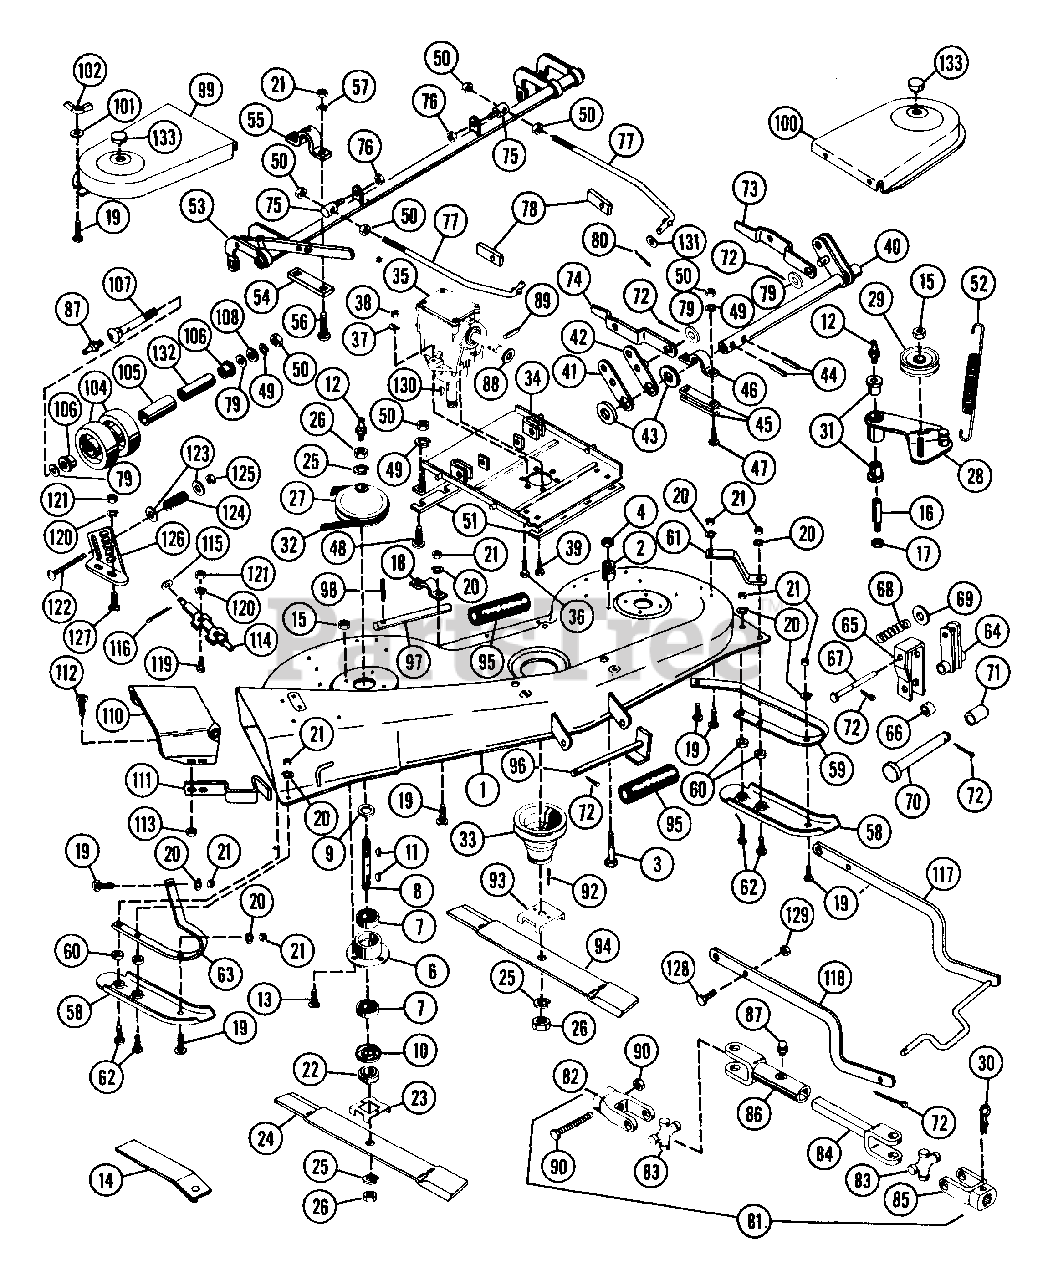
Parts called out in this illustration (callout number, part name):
1	60 INCH MOWER PAN W/ DECALS
2	SPRING ANCHOR
3	BLT-HEX .38-16X1.50 PL GR2
4	NUT-LK-CTR .375-16 GR A PL
6	HOUSING, SPINDLE
7	BRG-BALL .750X1.781X.61
8	SPINDLE SHAFT
9	WSHR-FL-STL .754X1.000X.032
10	BEARING SLINGER
11	KEY-WDRF .188X.625X.25 SAE 61
12	SPIN DRIVE ZERK FITTING
13	BLT-RDHDSQNK .38-16X.62 GR5 PL
15	NUT-LK-JAM-CTR .375-16 PL
16	IDLER STUD
17	NUT-LK-CTR .50-13
18	ROLLER CLAMP
19	BLT-RDHDSQNK .31-18X.75 GR5 PL
20	WSHR-LK .312X.097 PL HVY
21	NUT-HEX .312-18
22	RETAINER HUB
23	BLADE TRAY
24	MOWER BLADE 22 1/2
25	WSHR-LK .750X.188 MED PL
26	NUT-JAM .75-10 PL
27	SPINDLE SHEAVE
28	IDLER ARM
29	IDLER-FLAT 2.75 X .38 DAYCO
30	PIN-HAIR INT .18X1.18X3.25 PL
31	BSHG-FLG .625X.750X.500X.875BR
32	V-BELT, HA-WRAPPED
34	MOUNTING PLATE
35	MOWER GEAR CASE 48 IN
36	BLT-HEX .31-18X1.25 PL GR5
38	NUT-LK-TOP .312-18 GR C PL
39	SCR-TAP .312-18X1.0 THH PL TR
40	FRONT HANGER
41	OUTSIDE LINK
42	INSIDE LINK
43	WSHR-FL-STL .781X1.250X.059 PL
44	PIN-ROLL .250X1.25
47	BLT-RDHDSQNK .50-13X1.50 PL
48	BLT-RDHDSQNK .50-13X1.25GR5PL
49	WSHR-LK .500X.151 HVY PL
50	NUT .50-13 PL
52	SG-TENS .121X1.00X6.5 WLD 12
53	ROLLER FRAME
54	PAD
55	CLAMP
56	BLT-RDHDSQNK .31-18X1.00 PL
57	WSHR-LK .313X.093 MED HICLR
58	SKID
59	SKID BAR L.H.
60	SPACER .344X1.000X.375
61	BRACE
62	BLT-RDHDSQNK .31-18X1.50 GR5PL
63	SKID BAR R.H.
65	SUPPORT CHANNEL
66	SPACER .516X.749X.938
67	PIN-CLEV .498X4.31 YWZC
68	SG-COMP .62X.68X1.75
69	WSHR-FL-STL .531X1.062X.095 PL
70	PIN-CLEV .498X4.50 YWZC
71	SPACER .390X1.000X.562
72	PIN-COTR .12X1.0 PL
73	LEVELING LEVER L.H.
74	LEVELING LEVER R.H.
76	NUT-LK-CTR .50-13
77	ADJUSTMENT ROD
78	WEAR PLATE
79	WSHR-FL-STL .511X1.441X.125 PL
80	PIN-COTR .12X.75 PL
81	PTO ASSEMBLY
83	JOURNAL CROSS & BEARING ASSEMB
84	YOKE AND SHAFT
86	SLIP YOKE
87	SPIN DRIVE ZERK FITTING
88	WSHR-FL-STL .754X1.000X.032
89	PIN-ROLL .125X1.00
90	SHEARBOLT & NUT ASSEMBLY
92	PIN-GRV .188X.75 TP A
93	BLADE TRAY
94	BLADE
96	PIN WELDMENT
98	PIN-ROLL .250X1.00
99	BELT COVER R.H.
100	BELT COVER L.H.
101	WSHR-FL-STL .38X.875X.083 PL
102	NUT-WING W/INSERT .312 - 18
104	WHL 5 IN O.D.
105	WHEEL HUB
106	BRG-BALL .500X1.125X.500
107	WHEEL BOLT
108	WSHR-FL-STL .505X.880X.072 PL
110	CHUTE EXTENSION
111	SPRING, FLAT
112	BLT-RDHDSQNK .25-20X.50 SHT PL
113	NUT-LK-CTR .250-20 PL
114	HINGE PIN
115	WSHR-FL-STL.406X.812X.065PL
116	PIN-COTR .09X.75 PL
117	MOWER HANGER
118	HANGER ARM
119	BLT-SERRDHD SL .31-18X.75 YZ
120	WSHR-LK .312X.097 PL HVY
121	NUT-HEX .312-18
122	BLT-RDHDSQNK .31-18X1.75 PL
123	WSHR-FL-STL .38X.875X.083 PL
124	SG-COMP .063X.53X1.187
125	NUT-LK .312-18 GR A PL
126	QUADRANT
127	BLT-RDHDSQNK.31-18X.75GR5SHTPL
128	BLT-HEX .38-16X1.00 PL GR5
129	NUT-LK-CTR .375-16 GR A PL
130	KEY-WDRF .25X.750X.313 SAE91
131	WSHR-FL-STL .469X.937X.065 PL
132	SPACER .512X.747X3.396
133	BUTTON PLUG 1.0
